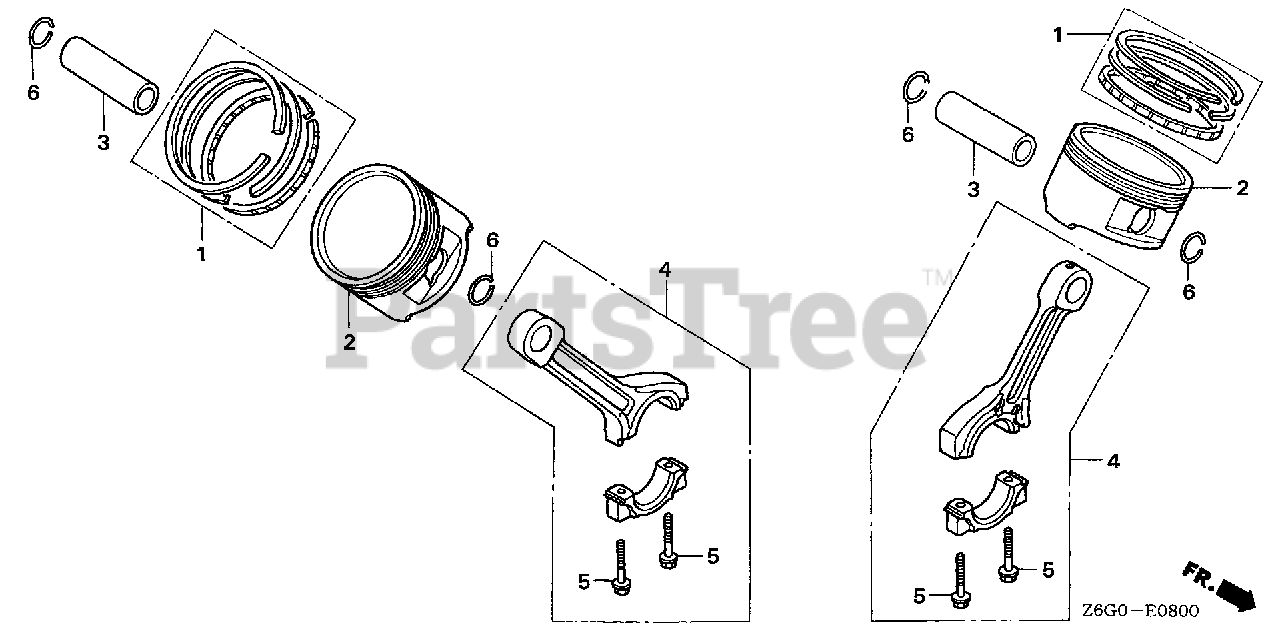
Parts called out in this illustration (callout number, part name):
1	RING SET, PISTON (STD)
1	RING SET, PISTON (STD.) (TEIKOKU)
1	RING SET, PISTON (OS 0.25)
1	RING SET, PISTON (0.25) (TEIKOKU)
1	RING SET, PISTON (OS 0.50)
1	RING SET, PISTON (0.50) (TEIKOKU)
1	RING SET, PISTON (0.75)
1	RING SET, PISTON (0.75) (TEIKOKU)
2	PISTON (STD.)
2	PISTON (STD)
2	PISTON (OS 0.25)
2	PISTON (0.25)
2	PISTON (OS 0.50)
2	PISTON (0.50)
2	PISTON (0.75)
3	PIN, PISTON
4	ROD ASSY., CONNECTING
5	BOLT, CONNECTING ROD (6X37)
6	CLIP, PISTON PIN (18MM)
